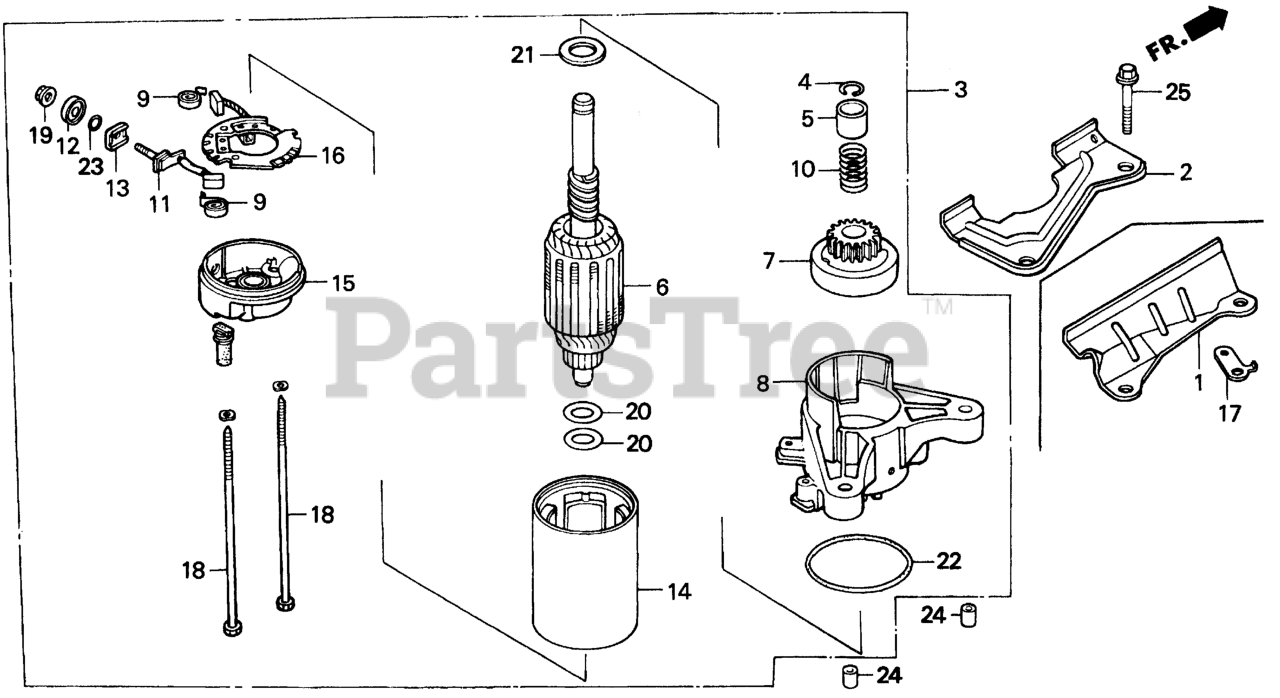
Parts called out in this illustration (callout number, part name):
1	PLATE, SIDE
17	STAY, WIRE CLIP (A)
25	BOLT, FLANGE (8X20)
